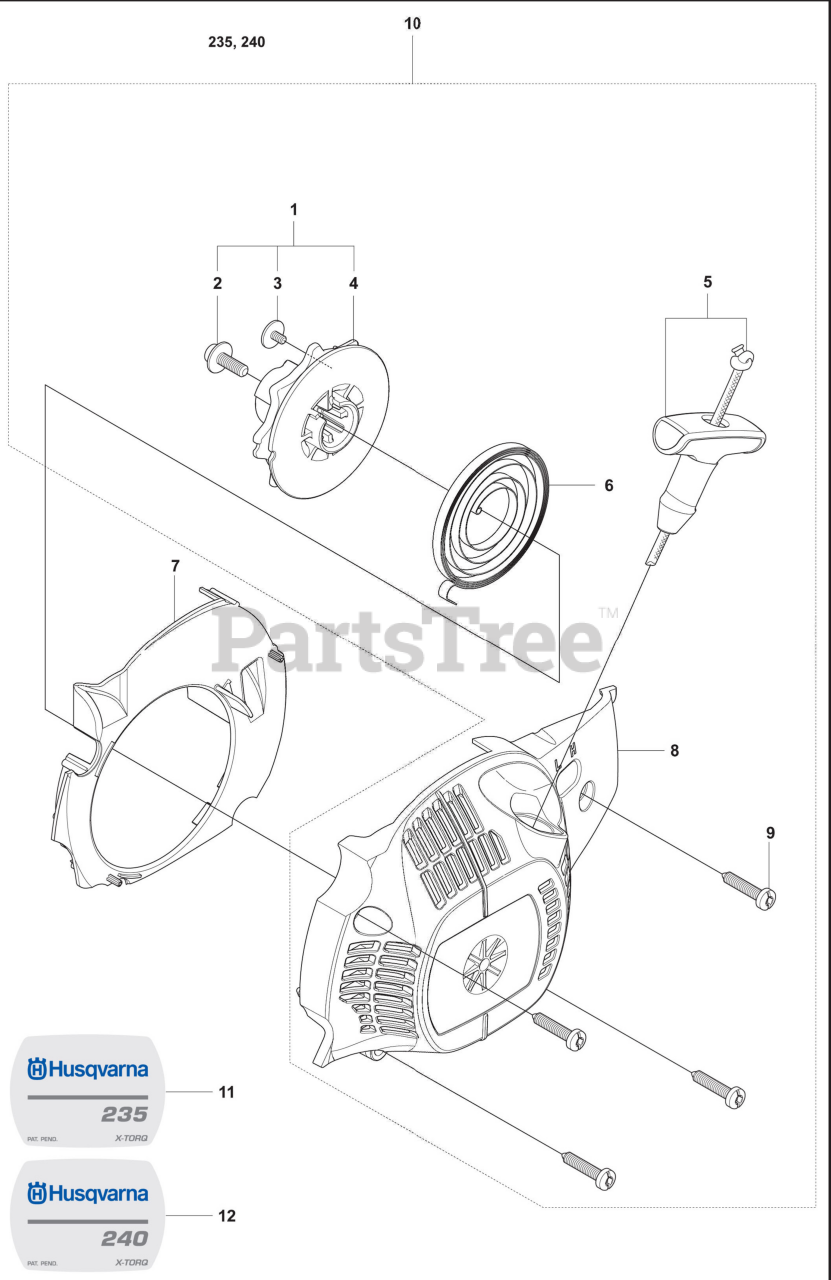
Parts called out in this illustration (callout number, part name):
1	KIT, STD STARTER 235,240
2	SCREW SHOULDER
3	SCREW, ROPE RETAINER
4	PULLEY- STARTER standard
5	HANDLE & ROPE assy
6	SPRING- RECOIL
8	FAN HOUSING
9	SCREW, FAN HOUSING
10	Kit complete 235/240
